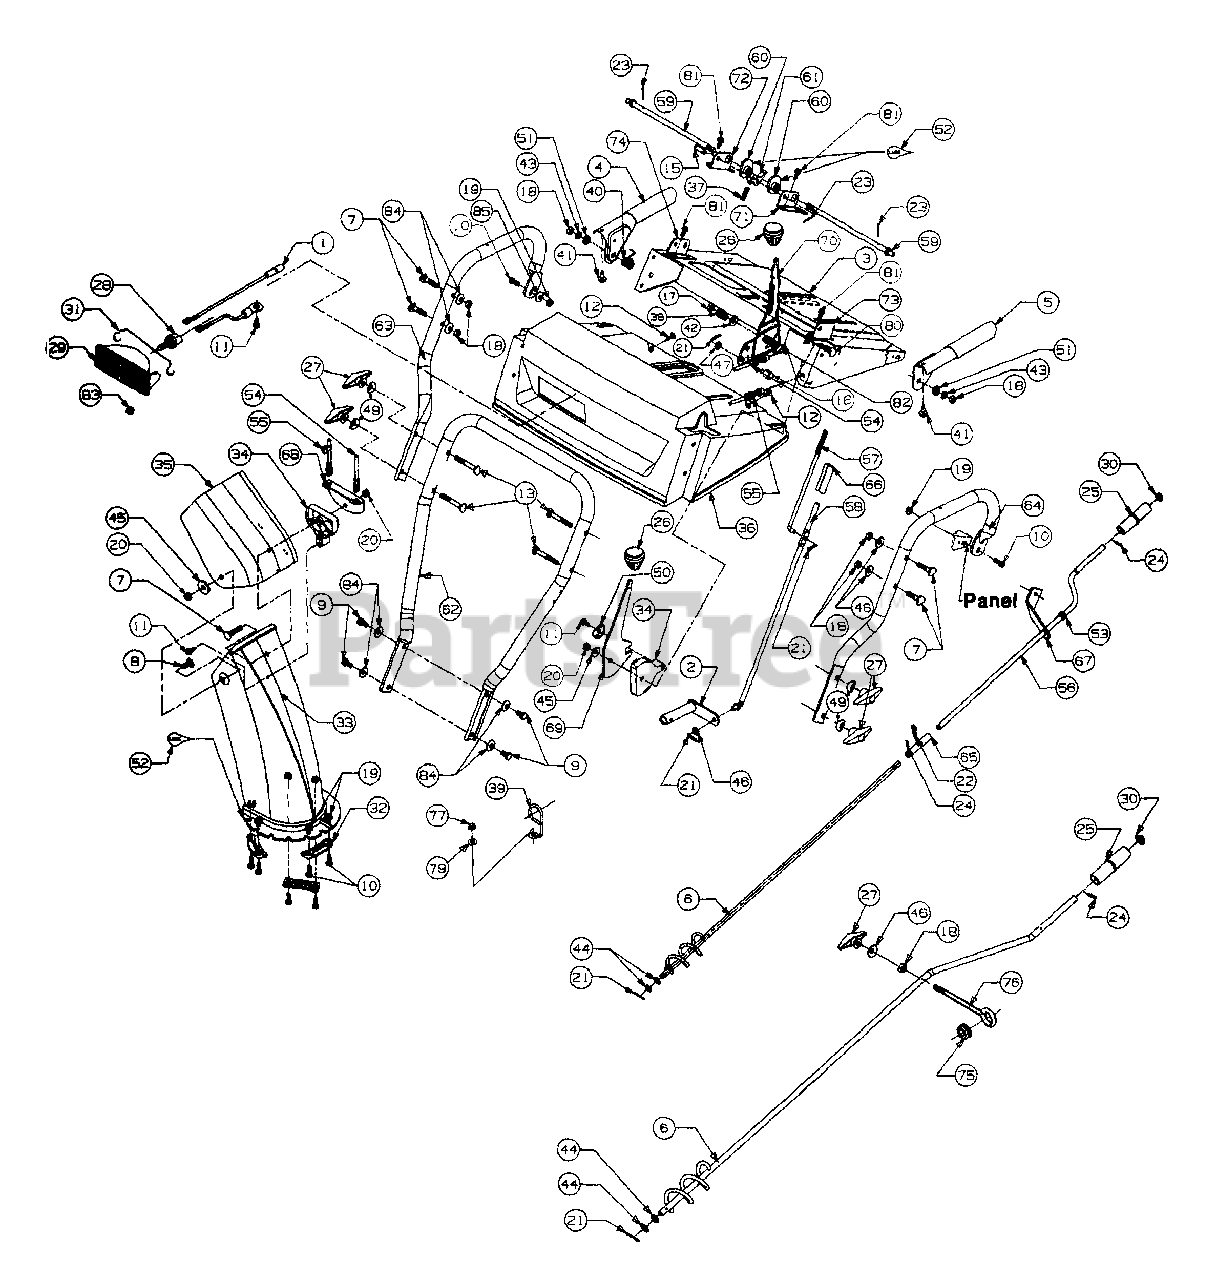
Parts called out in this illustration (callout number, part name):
1	Harness-Light
4	Handle-Engagement - R.H.
5	Handle-Engagement - L.H.
6	Crank-Chute
8	Bolt-Carriage
9	Screw-Hex
10	Screw-Hex
11	Screw-Washer Head-Hex
12	Screw-Hex
13	Bolt-Carriage
15	Pin-Clevis
16	Ferrule
17	Nut-Hex Lock
18	Nut-Hex
19	Nut-Hex Lock
20	Nut-Hex Lock
21	Pin-Cotter Internal
22	Pin-Cotter
23	Pin-Cotter
24	Pin-Roll
25	Knob-Chute Crank
26	Knob-Shift
27	Knob-Wing Nut
28	Lamp
29	Housing-Lamp
30	Cap-Push
31	Clip-Retaining
32	Keeper Chute
33	Chute-Lower
34	Guide-Cable
35	Chute-Upper
36	Panel-Handle
37	Spring
38	Spring
39	Wire-Control
40	Spring
41	Bumper
42	Washer-Bell
43	Washer-Lock
44	Washer-Flat
45	Washer
46	Washer-Bell
47	Washer-Flat
49	Washer-Saddle
50	Washer
51	Washer
52	Lubricant
53	Bushing-Plastic
54	Cable-Chute Control
55	Cable-Chute Control
56	Crank-Chute
57	Rod-Shift Upper
58	Rod-Shift Lower
59	Rod-Cam
60	Cam-Handle Lock
61	Pawl-Handle Lock
66	Connector
75	Grommet Rubber
76	Eyebolt-Chute
77	Nut-Hex Lock
79	Washer-Flat
80	Hex Screw
81	Hex Tap Screw
82	Hex Screw
83	Sems- Hex
84	Washer-Bell
85	Washer-Bell
